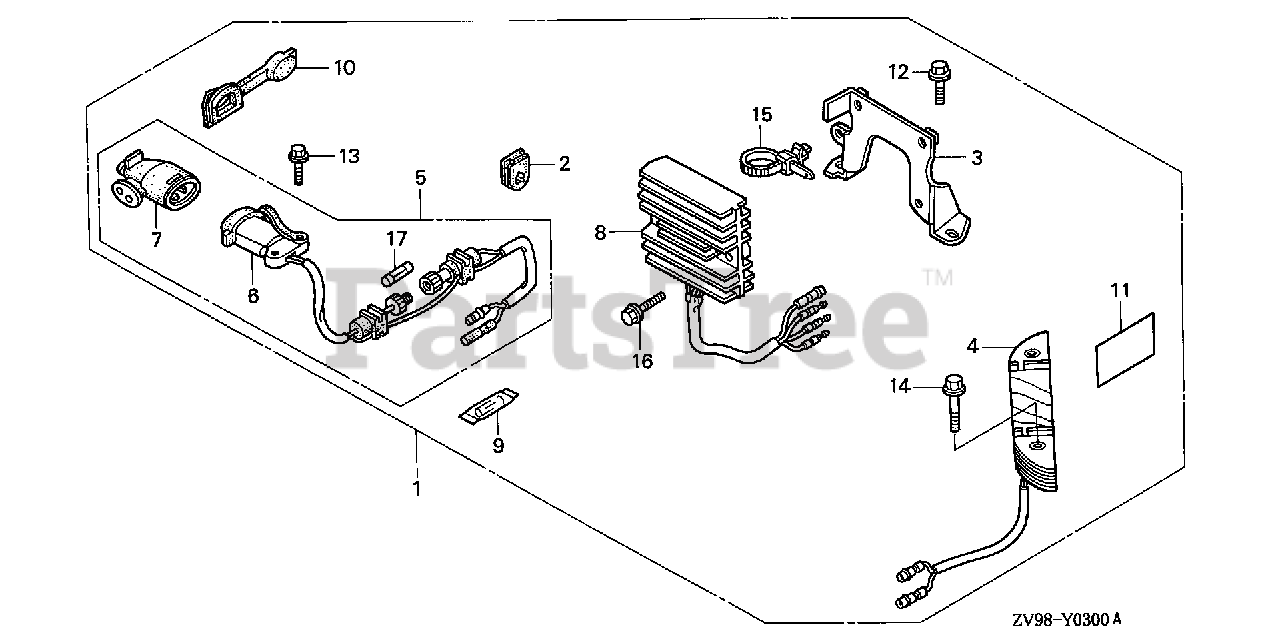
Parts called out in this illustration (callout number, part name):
1	RECEPTACLE KIT, CHARGE (6A)
2	GROMMET, WIRE
3	BRACKET, REGULATOR
4	COIL ASSY., CHARGE (12V-6A)
5	RECEPTACLE ASSY., CHARGE
6	RECEPTACLE
7	PLUG, RECEPTACLE
8	RECTIFIER ASSY., REGULATOR
9	FUSE, SPARE (15A)
10	GROMMET, CASE (LOWER) (C)
11	MARK, RECEPTACLE (6A)
12	BOLT, FLANGE (6X12)
13	BOLT, FLANGE (5X22)
14	BOLT, FLANGE (6X35)
15	STRAP, CABLE (118MM) (BLACK)
16	BOLT, FLANGE (6X20)
17	FUSE (15A)
